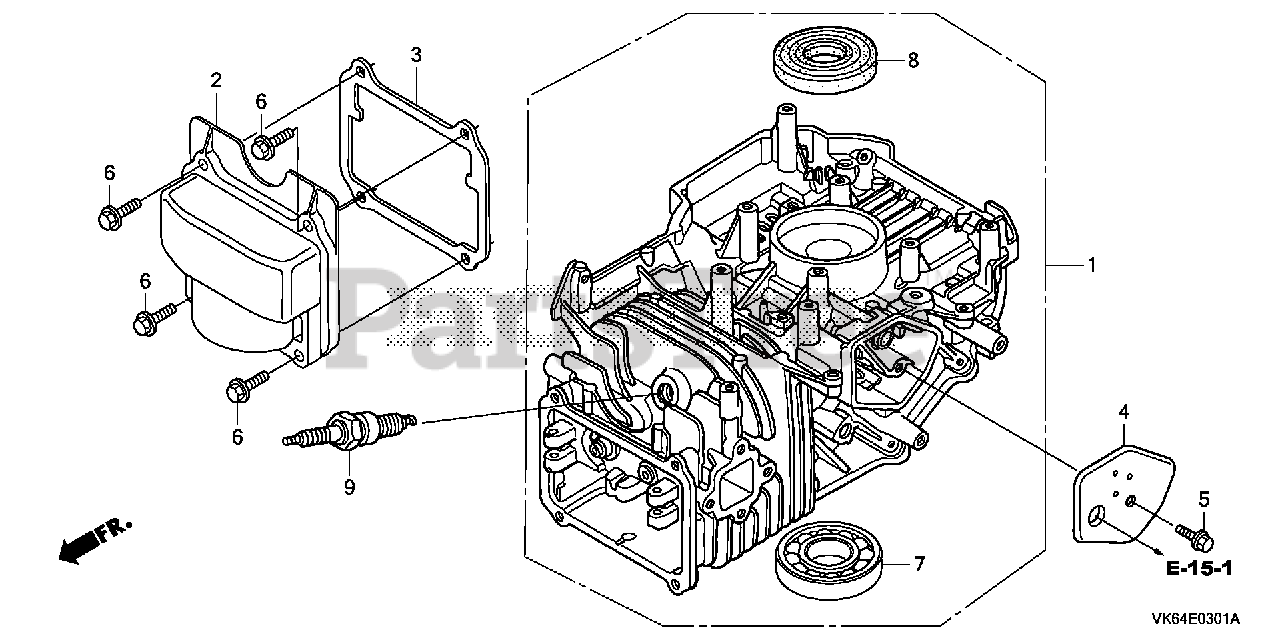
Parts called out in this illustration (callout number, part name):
1	CYLINDER ASSY.
2	COVER, CYLINDER HEAD
3	GASKET, HEAD COVER
4	COVER, BREATHER (Honda Code 5580006). (BREATHER VALVE ASSY.)
5	BOLT, FLANGE (6X14)
6	BOLT, FLANGE (6X25) Use up to Engine SN 2056819.
7	BEARING, RADIAL BALL
8	OIL SEAL (25.4X74X6)
9	SPARK PLUG (BPR6ES) (NGK)
